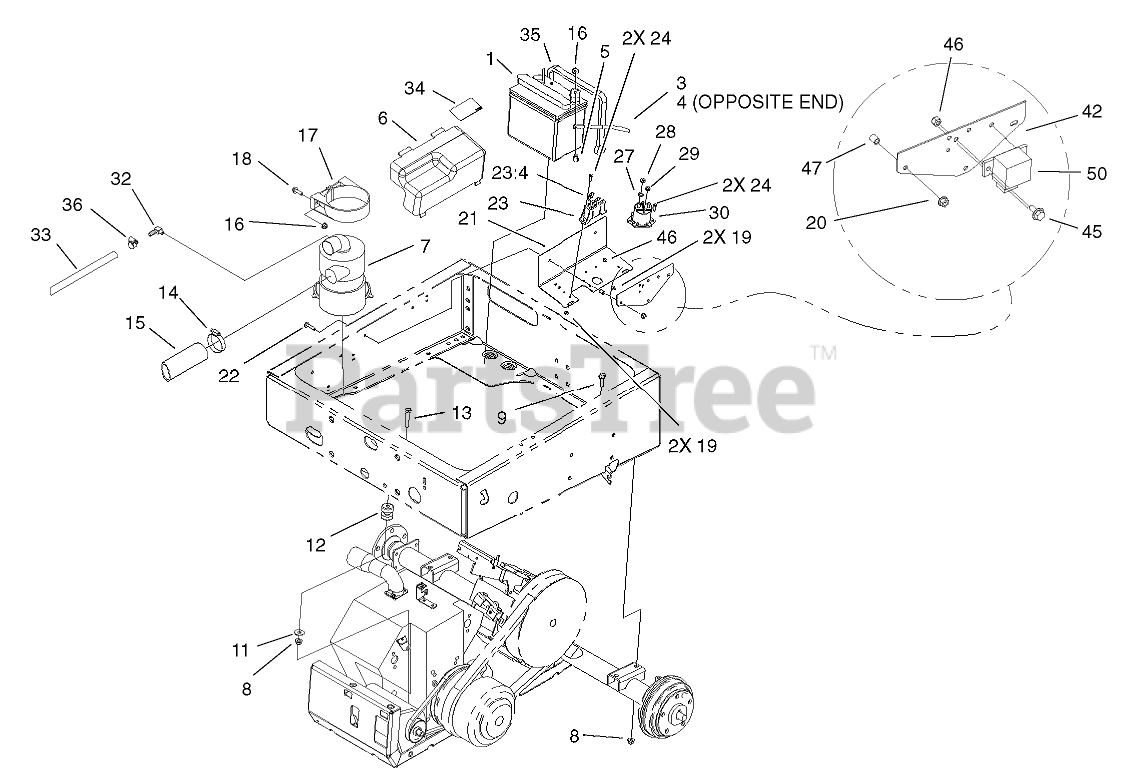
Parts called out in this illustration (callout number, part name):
1	BATTERY
3	CABLE-NEGATIVE
4	CABLE-POSITIVE
5	SCREW-HHF
6	COVER-ELECTRICAL
7	AIR CLEANER ASM
8	NUT-HF, NI
9	SCREW-HHF
11	WASHER-FLAT
12	MOUNT-ISO
13	SCREW-HH
14	CLAMP-HOSE
15	HOSE-INTAKE
16	NUT-HF, NI
17	BRACKET-MOUNTING
18	SCREW-HHF
19	NUT-LOCK, NI
20	NUT-HHF
21	MOUNT-COMPONENT
22	SCREW-HHF
23	Harness-Wire, Main
23:4	FUSE-BLADE, 10 AMP
24	SCREW-HWH
27	WASHER-LOCK
28	NUT-JAM
29	NUT-KEPS
30	SOLENOID
32	FITTING-90 DEG
33	HOSE-BREATHER
34	DECAL-INFORMATION
35	STRAP-EPDM
36	CLAMP-HOSE
42	BRACKET-IGNITION
45	SCREW-HHF
46	NUT-LOCK, NI
47	SPACER
50	RELAY
